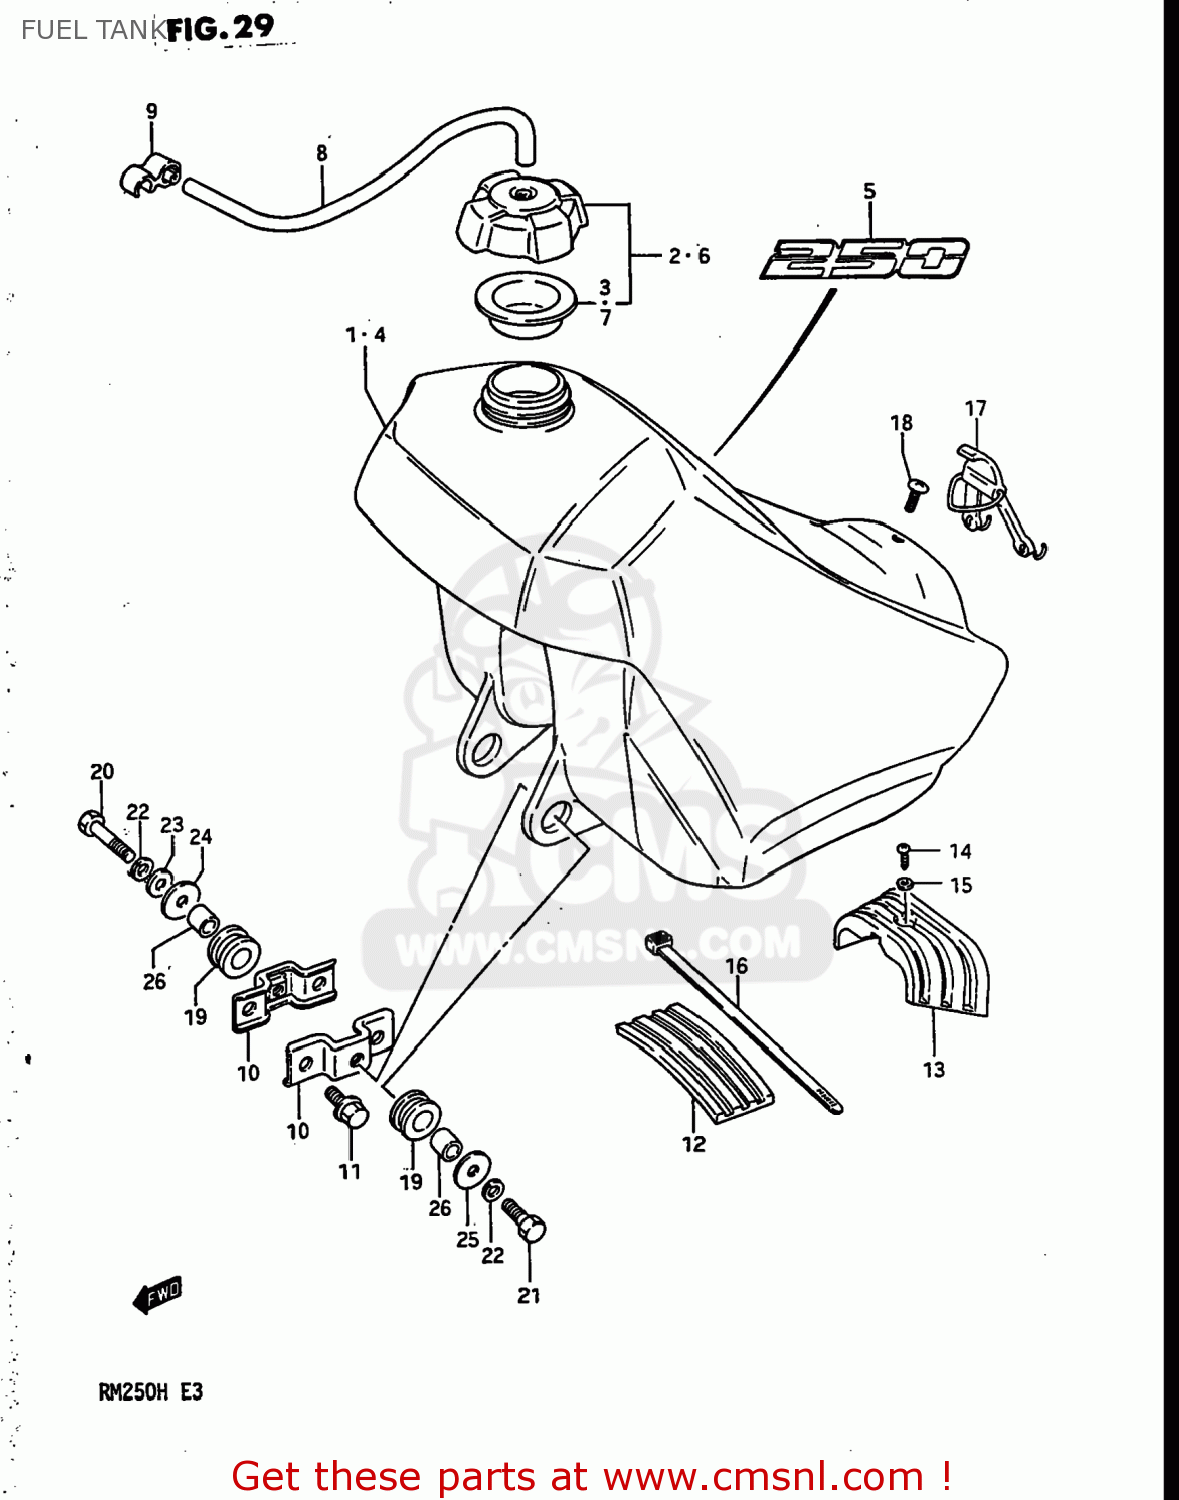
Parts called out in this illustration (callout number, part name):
1	TANK ASSEMBLY,FUEL
2	CAP SET,FUEL TANK
3	GASKET,FUEL TANK CAP (NAS)
4	TANK SET,FUEL
5	TAPE,FUEL TANK (250)
6	CAP SET,FUEL TANK
7	GASKET,FUEL TANK CAP (NAS)
8	HOSE
9	CLAMP,BREATHER HOSE
10	BRACKET,FUEL TANK
11	BOLT 8X16
12	CUSHION,FUEL TANK UPR FR
13	CUSHION,FUEL TANK
14	SCREW
15	WASHER
16	CLAMP
17	BAND,FUEL TANK RR
18	SCREW (6X15)
19	CUSHION
20	BOLT 8X50
21	BOLT
22	LOCK WASHER
23	WASHER
24	WASHER(8.5X26X1.2)
25	WASHER
26	SPACER(8.4X12X12)
